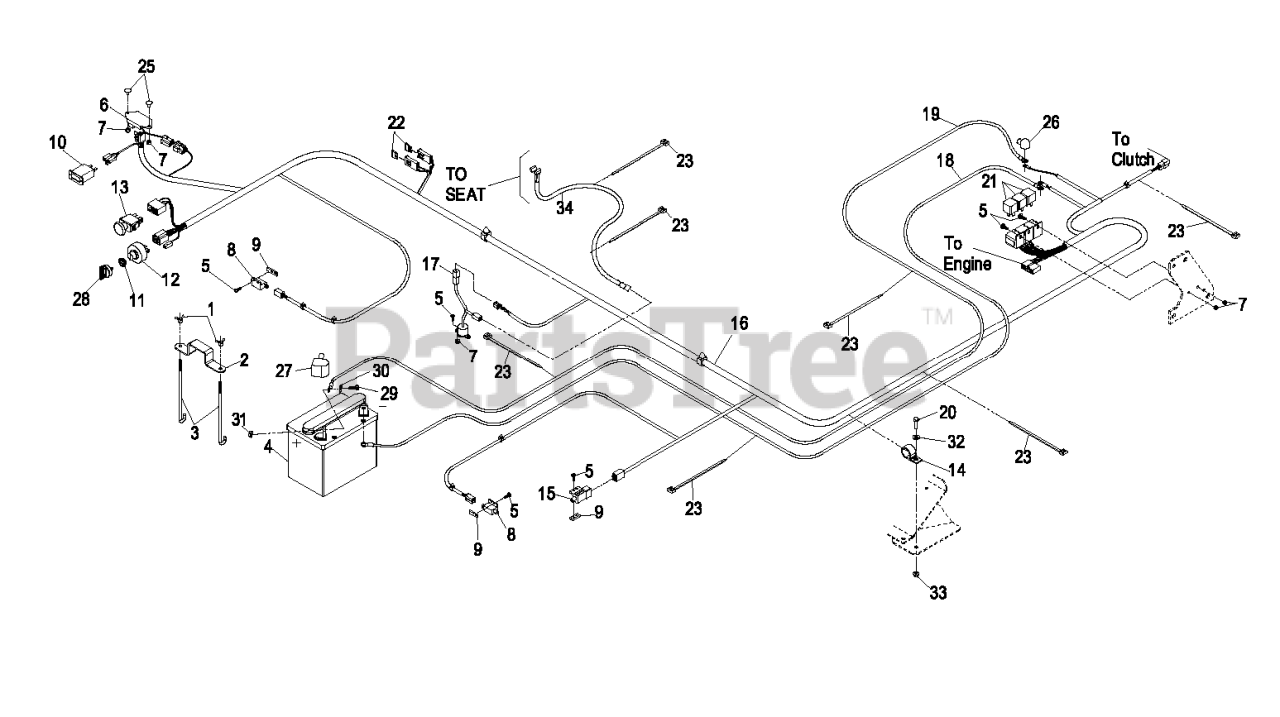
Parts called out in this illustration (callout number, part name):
1	WINGNUT
2	STRAP-HOLDDOWN
3	BOLT-HOLDDOWN
5	SCREW-PPH
6	MODULE-DELAY, SEAT
7	NUT-LOCK, NI
8	SWITCH-OPEN, NORMALLY
9	PLATE-TAPPED
10	METER-HOUR
11	NUT-SWITCH, IGNITION
13	SWITCH-PTO
14	CLIP-LOOM
16	HARNESS, WIRE XS
18	WIRE-GROUND
20	SCREW-HH
22	FUSE-BLADE TYPE, 20 AMP
23	TIE-PLASTIC
25	BOLT-CARR
26	INSULATOR-SOLENOID
28	Key, Exmark Logo
29	SCREW-HH
30	WASHER-FLAT
32	WASHER-PLAIN
34	HARNESS-WIRING, SEAT
